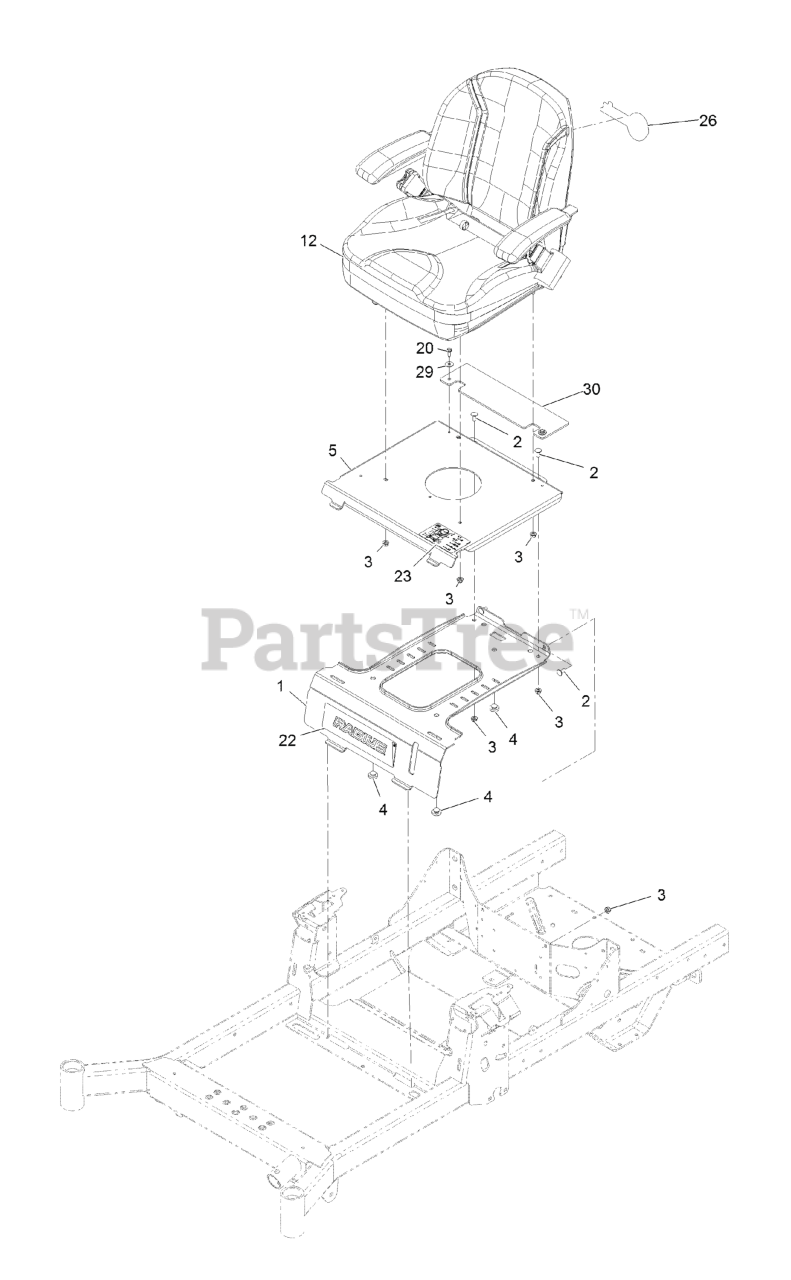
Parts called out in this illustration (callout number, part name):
1	PLATE-RETAINER, TANK
2	SCREW-CARR
3	NUT-HF, NI
4	BUMPER-RUBBER
5	PLATE-SEAT, FIXED
12	ASM-SEAT EXMARK
20	SCREW-HWH, THREAD ROLL
22	DECAL-RADIUS LOGO
23	DECAL-AID, SERVICE
26	DECAL-EXMARK LOGO
30	GUARD, RUBBER
